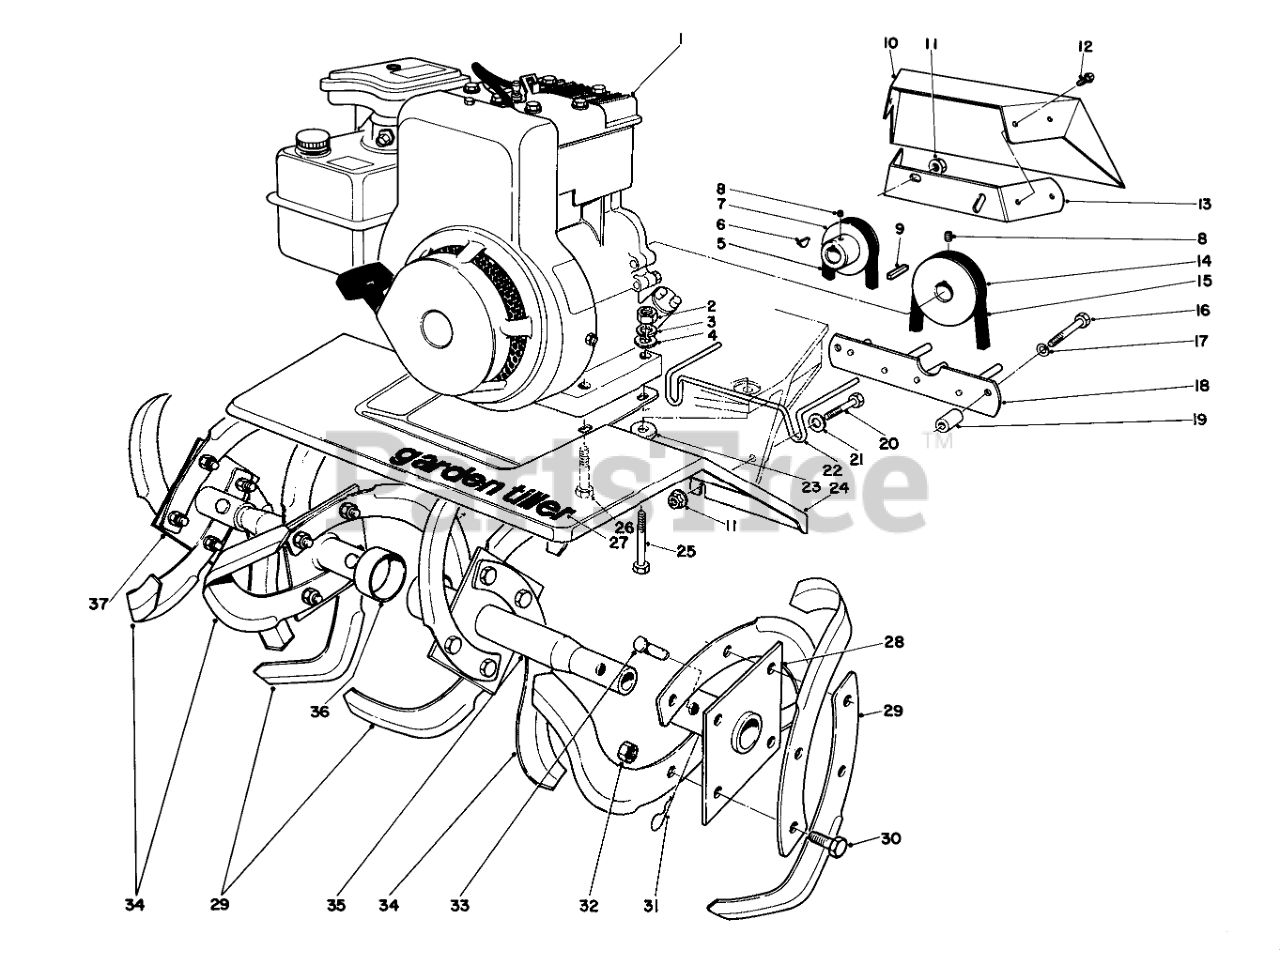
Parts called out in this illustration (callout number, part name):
1	Engine
2	NUT-HEX
3	WASHER-LOCK
4	WASHER-PLAIN
5	V-BELT
6	HI PRO KEY
7	Pulley-Engine Rev.
8	SCREW-HSH
9	KEY-SQUARE
10	PULLEY GUARD
11	NUT-LOCK, HHF
12	SCREW-HWHTF
13	Strap-Belt Shield
14	ENGINE PULLEY
15	V-BELT
16	SCREW-HH
17	WASHER-LOCK
18	Belt Guide
19	Spacer
20	SCREW-HH
21	WASHER-FLAT
22	Belt Guide-Worm Shaft
23	WASHER-FLAT
24	TINE SHROUD
25	SCREW-HH
26	SCREW-HH
27	Decal
28	Axle L.H.Outer
29	RH TINE
30	SCREW-HH
31	PIN-COTTER
32	NUT-KEPS
33	TINE PIN
34	LH TINE
35	Axle L.H. Inner
36	Axle R.H. Inner
37	Axle R.H. Outer
